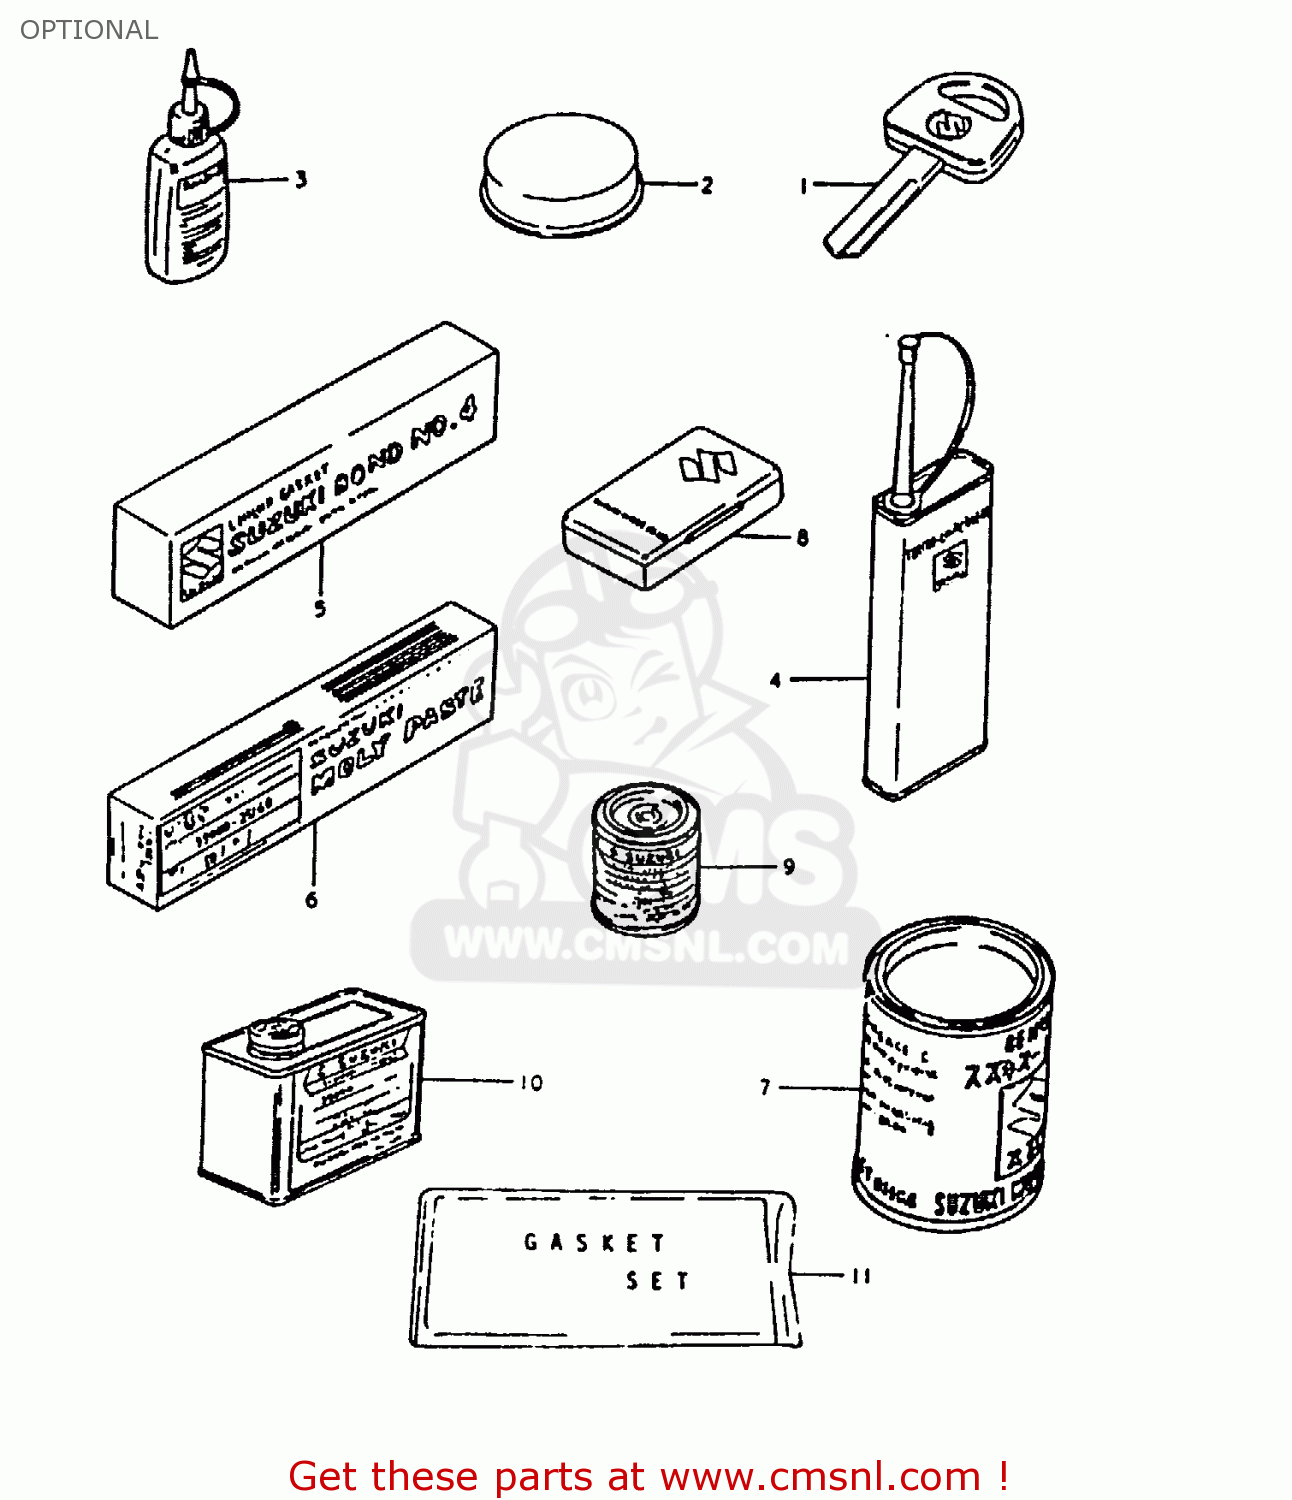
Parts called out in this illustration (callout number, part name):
1	KEY,BLANK
2	GREASE,PBC FOR BRK PAD 20G
3	THREAD LOCK SUPER (1332B)
4	THREAD LOCK NO.1401 CLEAR 200G
5	BOND 1104
6	SUZUKI MOLY PASTE
7	GREASE(C)EP2 LITHIUM 150G
8	TUBE REPARING TOOL
9	PAINT,BLACK
10	PAINT (BLACK)
11	GASKET SET
